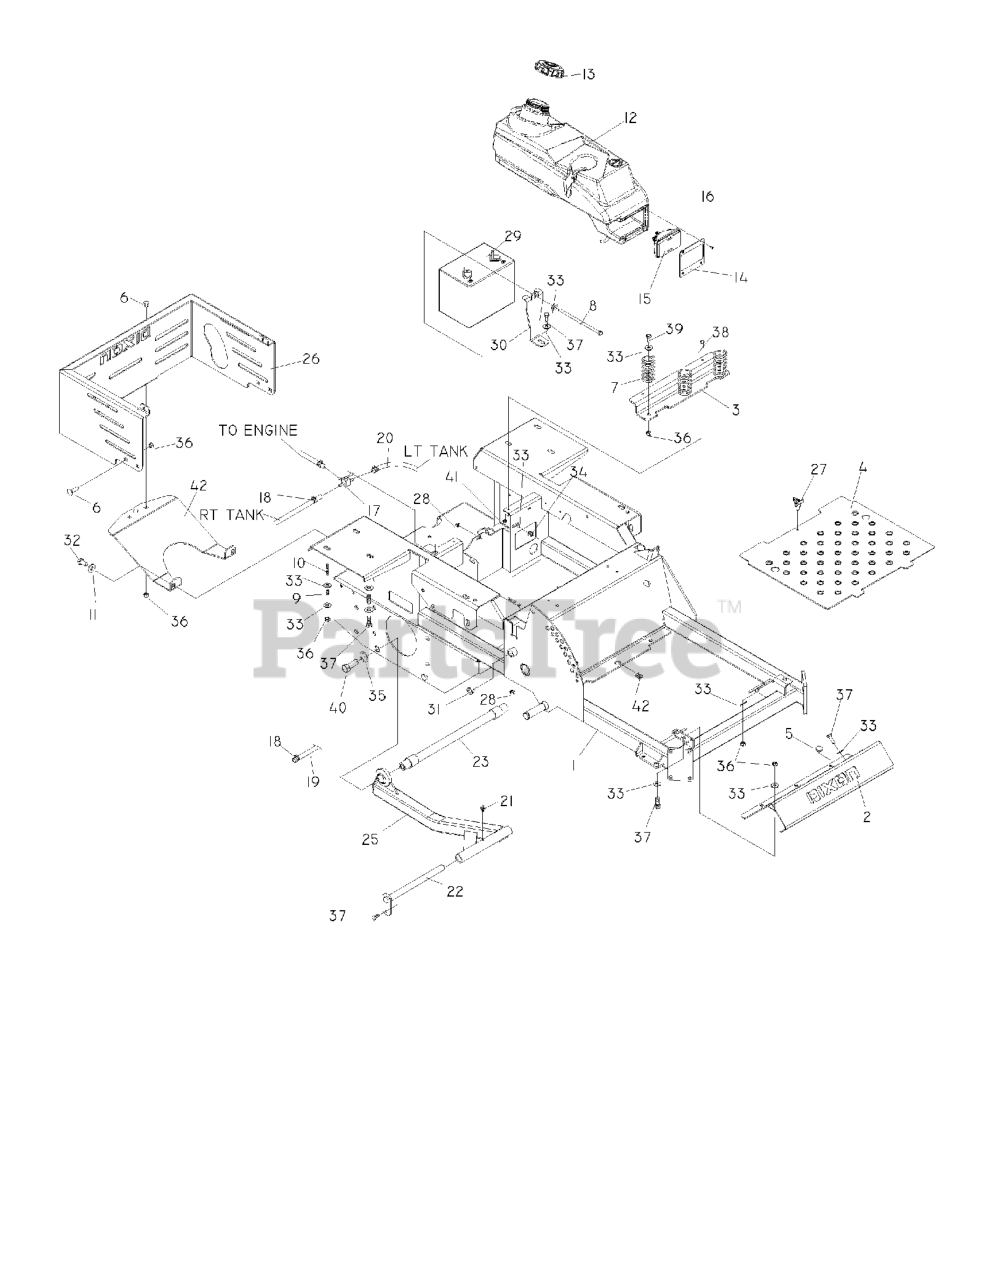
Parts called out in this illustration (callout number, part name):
1	FRAME W/DECALS KODIAK CE
2	FOOT REST
3	SPRING MOUNT
4	FOOT PLATE W/DECALS KODIAK CE
5	GROMMET, BUMPER
6	BOLT 5/16C X 3/4" CARRIAGE
7	SEAT SPRING
8	HCS 5/16-18 X 6 GR 5 ZD
10	STUD, 5/16C
11	WASHER 3/8 FLAT
12	TANK, FUEL, LT
13	FUEL CAP ANTI-SPLASH
14	PLATE LIGHT
16	SCR #10-24 X 3/8 SKT HD BLK OX
17	FUEL VALVE
18	HOSE CLAMP
19	FUEL LINE 24"
20	FUEL LINE 34"
21	ZERK
22	PIVOT PIN
23	STRUT MOUNT WELDMENT
24	PLATE, SKID
25	STRUT, RIGHT
26	GUARD, REAR W/DECALS
27	KNOB W/STUD
28	5/16-18 NYLOC FLANGE NUT
29	BATTERY, 12 V 330 AMP TBR
30	BRKT, HOLD DOWN, BATTERY
31	BUSHING
32	HCS 3/8C X 1
33	WASHER 5/16 FLAT
34	NUT 5/16C CENTERLOCK
35	LOCKWASHER 5/8
36	NUT 5/16 NYLOC
37	HCS 5/16C X 1
38	HCS 1/4C X 3/4 HCS
39	SCREW 5/16C X 1 HEX CAP
40	HCS 5/8C X 2 GR.5
41	NUT 1/4-20 NYLOC
42	U-CLIP 5/16-18 NUT RETAINER
